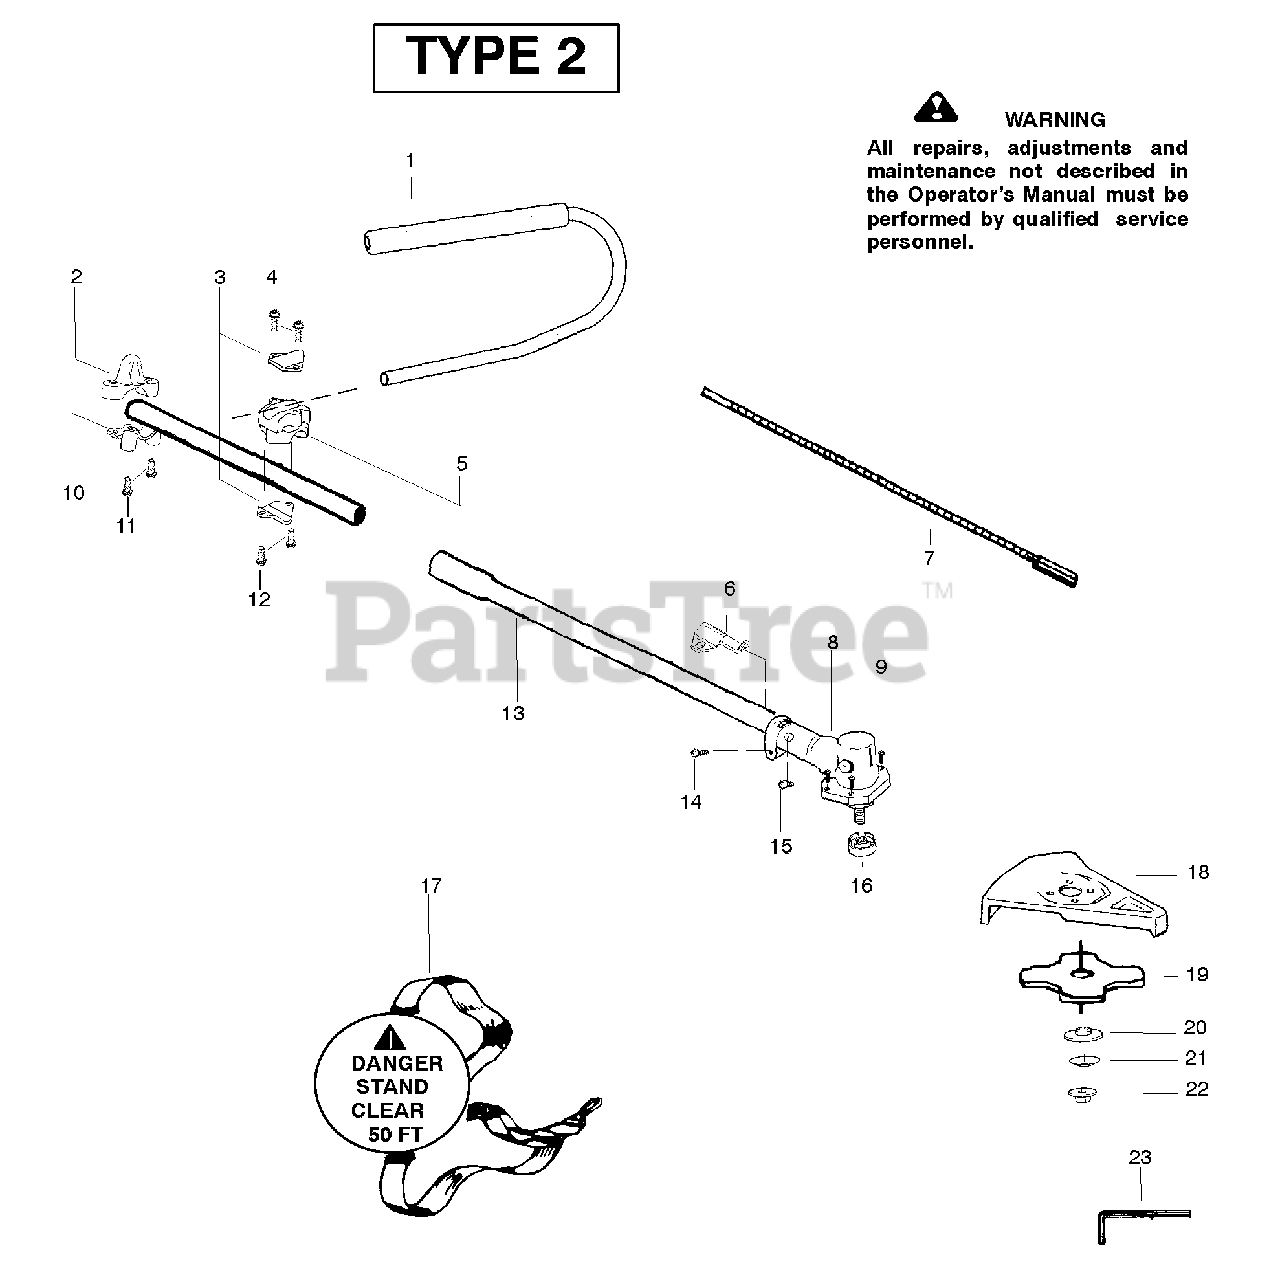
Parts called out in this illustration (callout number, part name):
1	Kit-Handlebar
2	Clamp-Harness Upper
3	Clamp-Bracket
5	Clamp-Handlebar (7/8")
5	Clamp-Handlebar (1")
6	Bracket-Shield
7	Flexshaft-Split boom
8	Assy-Gearbox
10	Clamp-Harness Lower
13	Assy.-Driveshaft
15	Screw-Alignment
16	Dust cup - Blade
17	Assy-Shoulder Strap
18	Kit-Blade Shield
19	Accy.-Weed Blade (8")
20	Washer-Blade Retaining
21	Washer-Belleville
22	Nut-Flange
23	Wrench-Hex (5/32")
